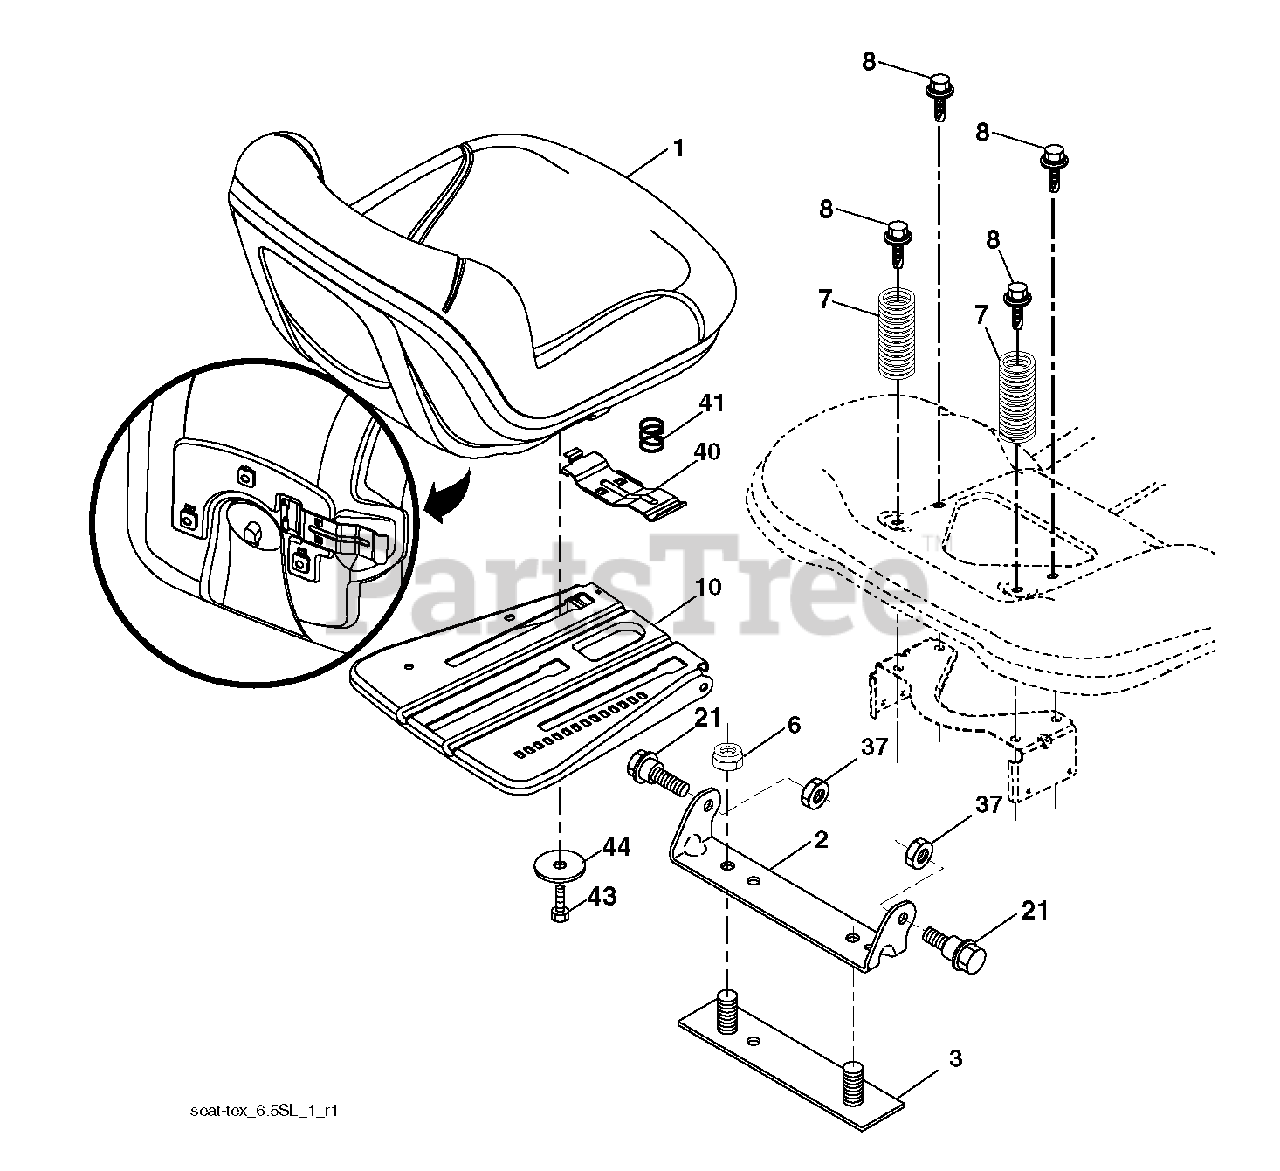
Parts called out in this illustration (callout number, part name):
1	SEAT.TH154.GREY.HUS.ARMREST
2	BRKT.PIVOT.FENDER
3	STRAP
6	NUT
7	SPRING COMPRESSION
8	BOLT, 5/16-18 X 1 3/4
10	PAN.ASM.SEAT.3PT
21	BOLT.SHOULDER.5/16-18
37	NUT.71038.31-18.HEX.NYLOCK
40	HANDLE.SLIDE.SEAT.TEX.BLACK
41	SPRING.LATCH.SEAT.TEX
44	WASHER 13/32 X 2-3/8 X 12GA
